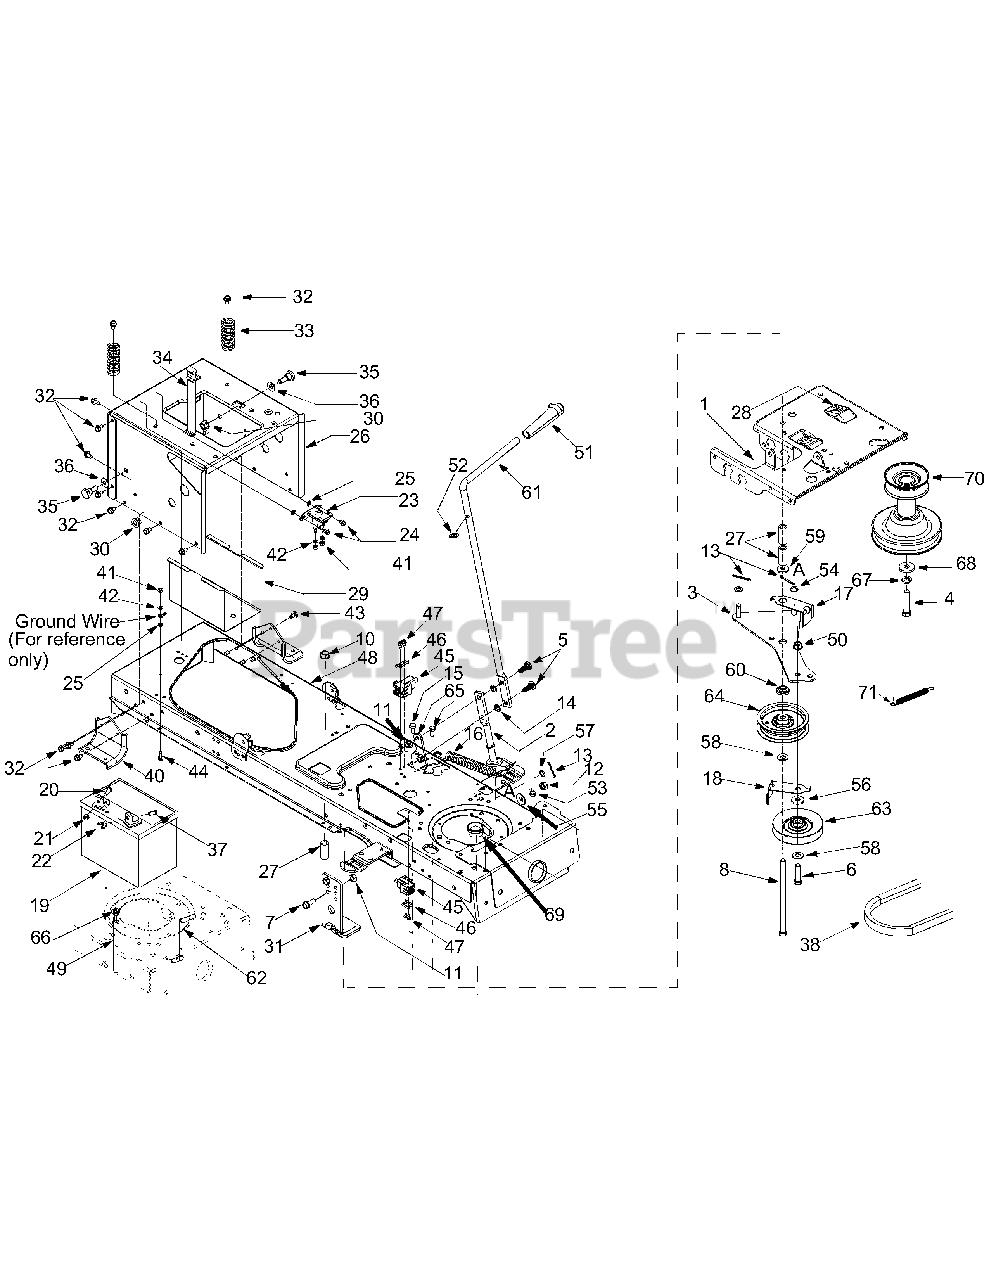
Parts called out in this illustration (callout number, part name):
2	PTO Lever Engagement Assembly
3	Engagement Plate Assembly
4	Hex Bolt 7/16-20 x 2.0
5	Carriage Screw 5/16-18 x 1.0
6	Hex Screw 3/8-16 x 1.5
7	Screw, 5/16 x .75
8	Hex Screw 3/8-16 x 7.0
10	Flange Lock Nut
11	Flange Lock Nut
12	Hex Nut
13	Cotter Pin
14	Speed Nut
15	Hex Cap Screw 5/16-18 x .625
16	Extension Spring
17	Belt Guard
18	Belt Guard
19	12 V Battery
20	Hex Cap Screw, 1/4-20 x .62
21	Hex Sems Nut, 1/4-20
22	Wing Nut, 1/4-20
23	Solenoid, 12-Volt, 100 Amp
24	Self Tapping Screw, 1/4-20 x .5
25	Lock Washer, 1/4
28	Hex Split Flange Bearing
32	Self Tapping Screw, 5/16-18 x .625
33	Compression Spring, 1.28 x 3.5
34	Battery Strap
35	Shoulder Screw, .625 x .5, 7/16-20
36	Bell Washer, .45 x 1.0 x .062
37	Shoulder Screw
38	PTO Belt
41	Hex Nut 1/4-20
42	Lock Washer
43	TT Screw 5/16-18 x 0.5
44	TT Screw 1/4-20 x 0.75
45	Switch
46	Switch Plate
47	AB Screw #10-16 x 0.5
50	Push Nut Retainer
51	PTO Knob
52	Flat Washer
53	Lock Washer
54	Flat Washer
55	Bell Washer
56	Flat Washer
57	Flat Washer
58	Flat Washer
59	Flat Washer
60	Shoulder Spacer
62	Belt Keeper Rod
63	Idler Pulley
64	Idler Pulley
66	Lock Washer
67	Lock Washer
68	Flat Washer
69	Spacer
70	Engine Pulley
71	Extension Spring
